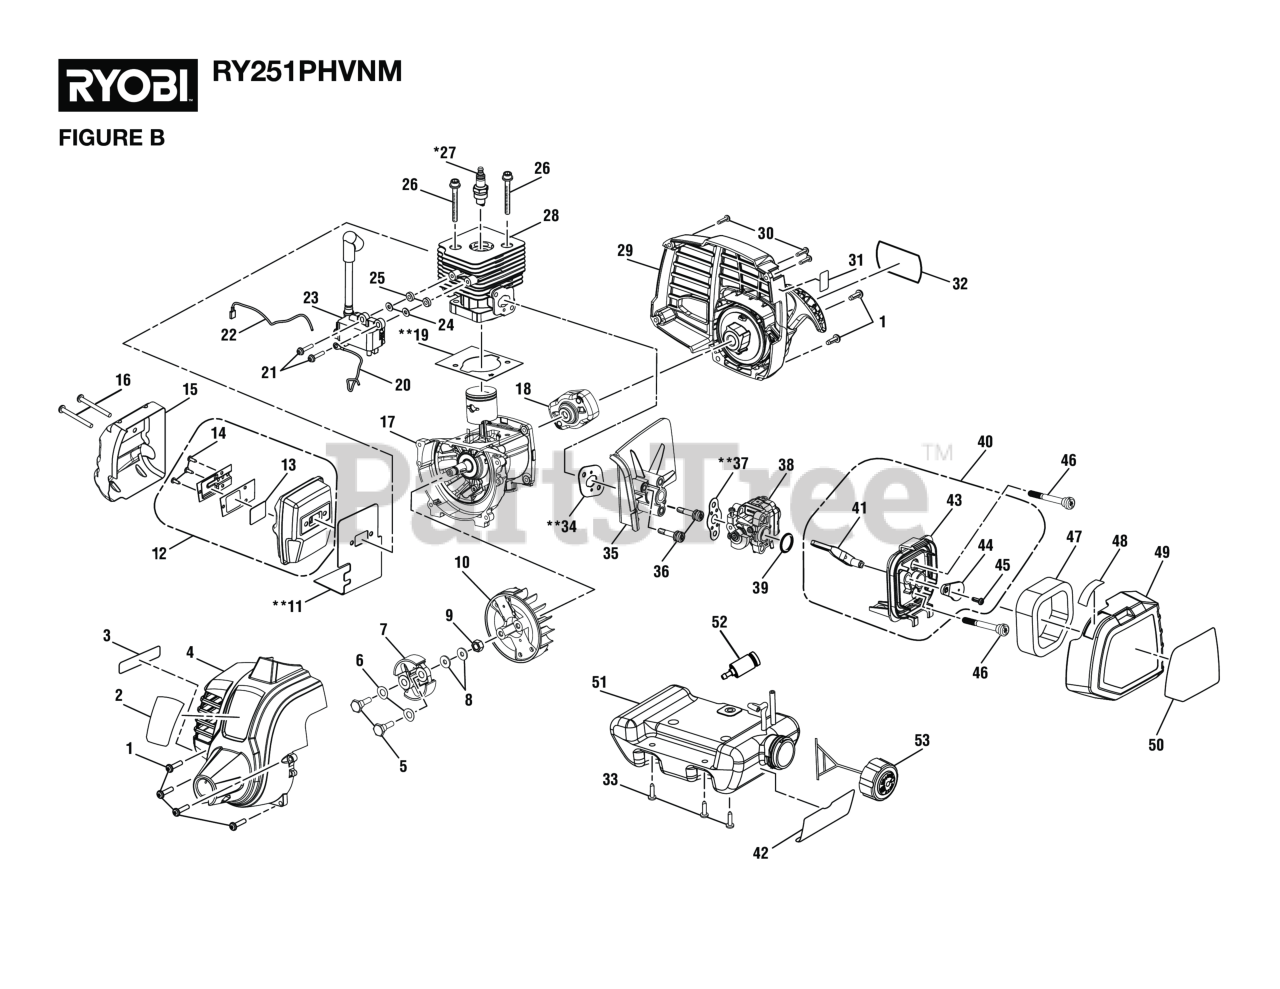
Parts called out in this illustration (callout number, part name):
1	Cap Screw w/Washer (M5 x 16 mm, T25 Torx Soc. Hd.)
2	Logo Label (Front)
3	Warning Label (Combustion)
4	Front Housing Assembly w/ Labels
5	Clutch Shoulder Bolt (M6 x 22.5 mm, Hex Hd.)
6	Washer (Curved)
7	Clutch Assembly
8	Washer (ID6 x OD15 x 1.2t)
9	Flange Nut (M8, Flywheel)
11	Muffler Gasket
12	Muffler Assembly
13	SCREEN
14	Screw (6-20 x 1/4 in., T20 Torx Pan Hd. S.T.)
15	HEAT SHIELD
16	Screw (M5 x 50 mm, Torx Slotted Recessed Pan Hd.)
17	Crankcase Assembly
18	Starter Cup
19	Gasket
20	Lead Wire Assembly, Red
21	Screw (M4 x 22 mm, T20 Torx Slotted Recessed Pan Hd.)
22	Lead Wire Assembly, Black
24	Flat Washer (OD10 x ID42 x 1t)
25	Phenolic Spacer (Ignition Module)
26	Screw (M5 x 22 mm, T25 Torx Soc. Hd.)
27	Spark Plug (Champion RCJ6Y)
29	Screw (M4 x 18 mm, T20 Torx Pan Hd. S.T.)
30	Screw (M4 x 20 mm, T20 Torx Pan Hd. S.T.)
31	Primer Bulb Location Label
32	Shoulder Screw (M4 x 14 mm, T25 Torx Truss Hd.
33	Shoulder Screw w/Washer (M4 x 14 mm, T25 Torx Truss Hd.)
34	Heat Dam Insulator
35	Screw (M5 x 30 mm, T25 Torx Pan Hd. S.T.)
36	Screw w/Washers (M5 x 30 mm, T25 Torx Pan Hd.)
37	Gasket
38	Carburetor Assembly
39	Carburetor O-Ring
40	Airbox Base Assembly
41	Compression Limiters
42	Fuel Mixture Label
43	Air Box Base
44	Screw (M4 x 12 mm, T20 Torx Pan Hd. S.T.)
45	Screw (M4 x 12 mm, Slotted Recessed Pan Hd.)
46	Screw (M5 x 45 mm, T20 Torx Truss Hd.)
47	Air Filter (Element)
48	Choke Position Label
49	Airbox Cover (Inc. Key Nos. 48 & 50)
50	Starting Instructions Label
51	Fuel Tank and Cap Assembly
52	Fuel Filter
53	Fuel Cap Assembly
